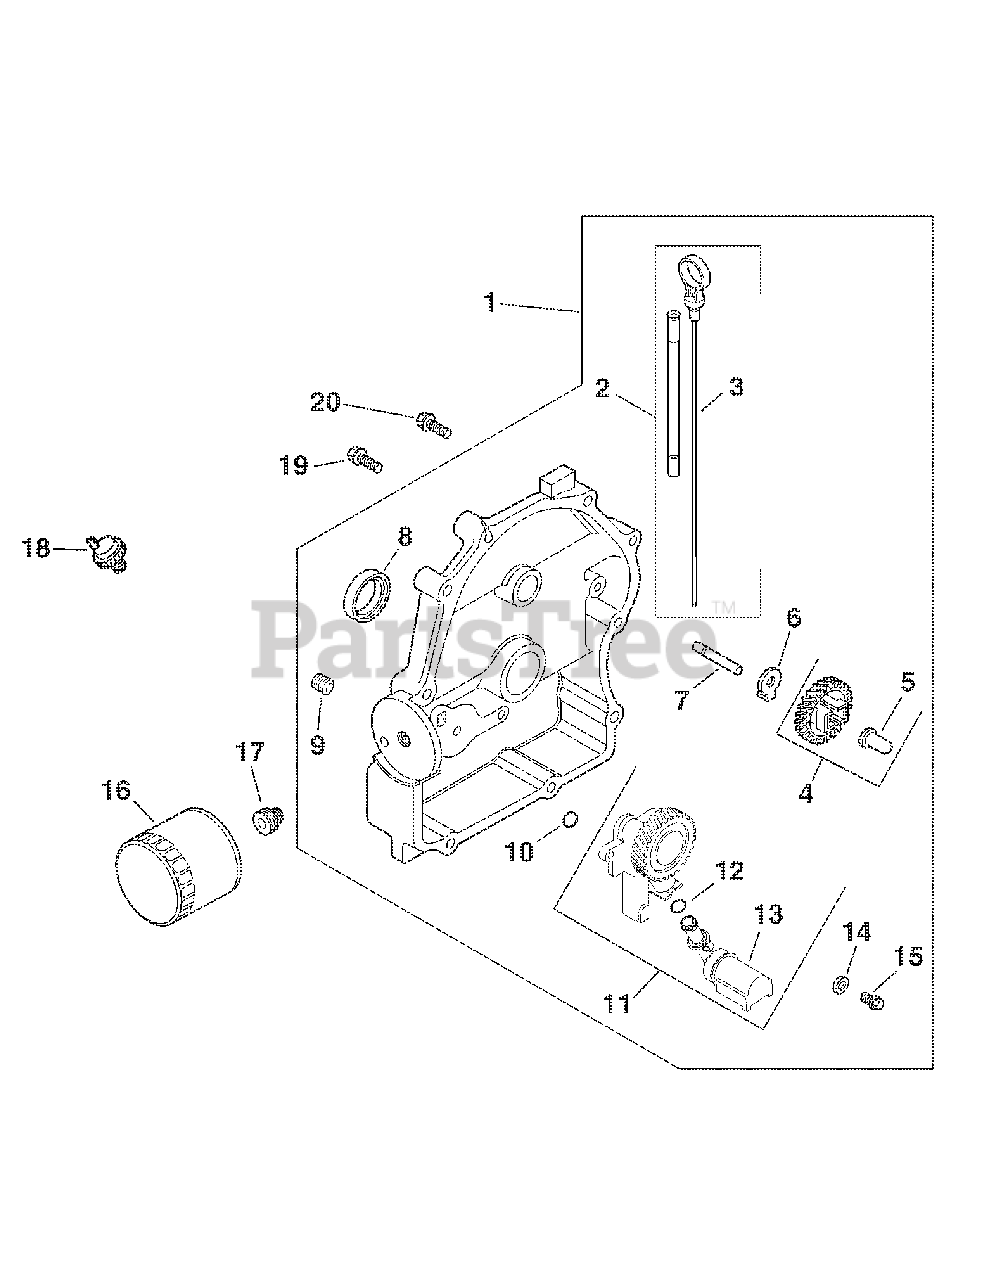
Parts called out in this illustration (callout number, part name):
1	Plate, closure assembly (Includes 2-15)
2	Kit, tube w/dipstick (Includes 3)
4	Kit, governor gear (Includes 5)
5	Pin, governor regulating
7	Shaft, governor gear
8	Seal, oil (PTO end)
9	Plug, pipe 1/8" (2)
11	Oil pump assembly (Includes 12, 13)
12	O-Ring, oil pick-up
13	Pick-up, oil
14	Washer, plain 6 mm
15	Screw, hex. Flange M6x1.0x25 (2)
16	Filter, oil
17	Nipple, oil filter
18	Switch, pressure
19	Screw, hex. Flange M8x1.25x45 (9)
20	Screw, hex. Flange M8x1.25x45
